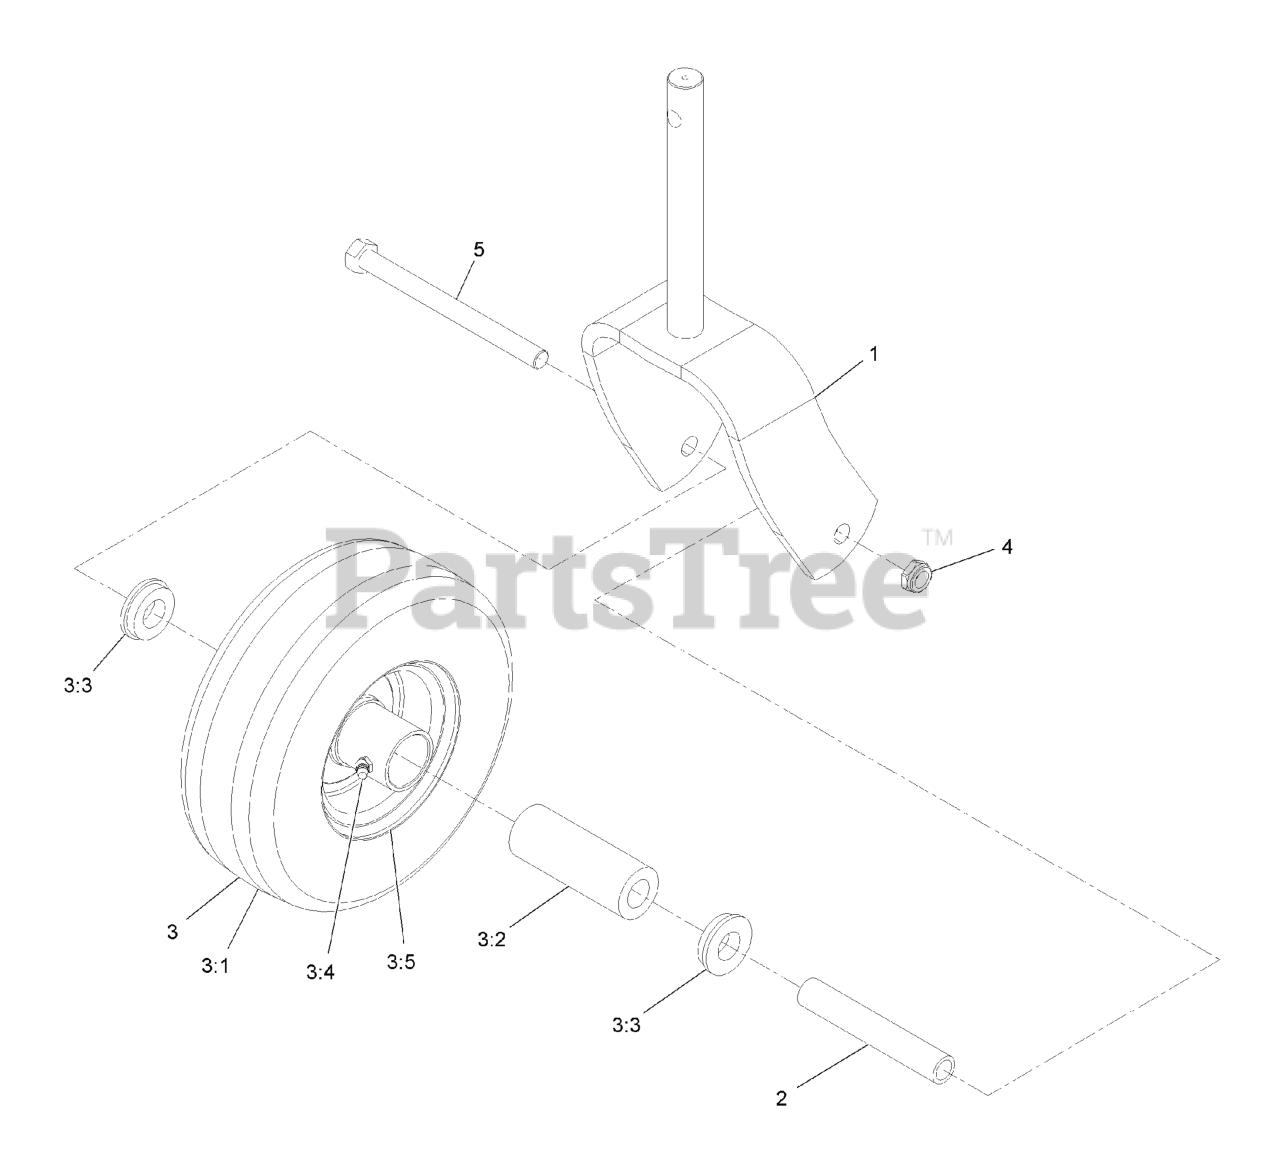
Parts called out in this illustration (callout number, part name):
1	FORK-CASTER
3	WHEEL AND TIRE ASM
3:1	Tire
3:2	BEARING
3:3	BUSHING
3:4	FITTING-GREASE
3:5	Wheel
4	NUT-HEX
5	SCREW-HH
